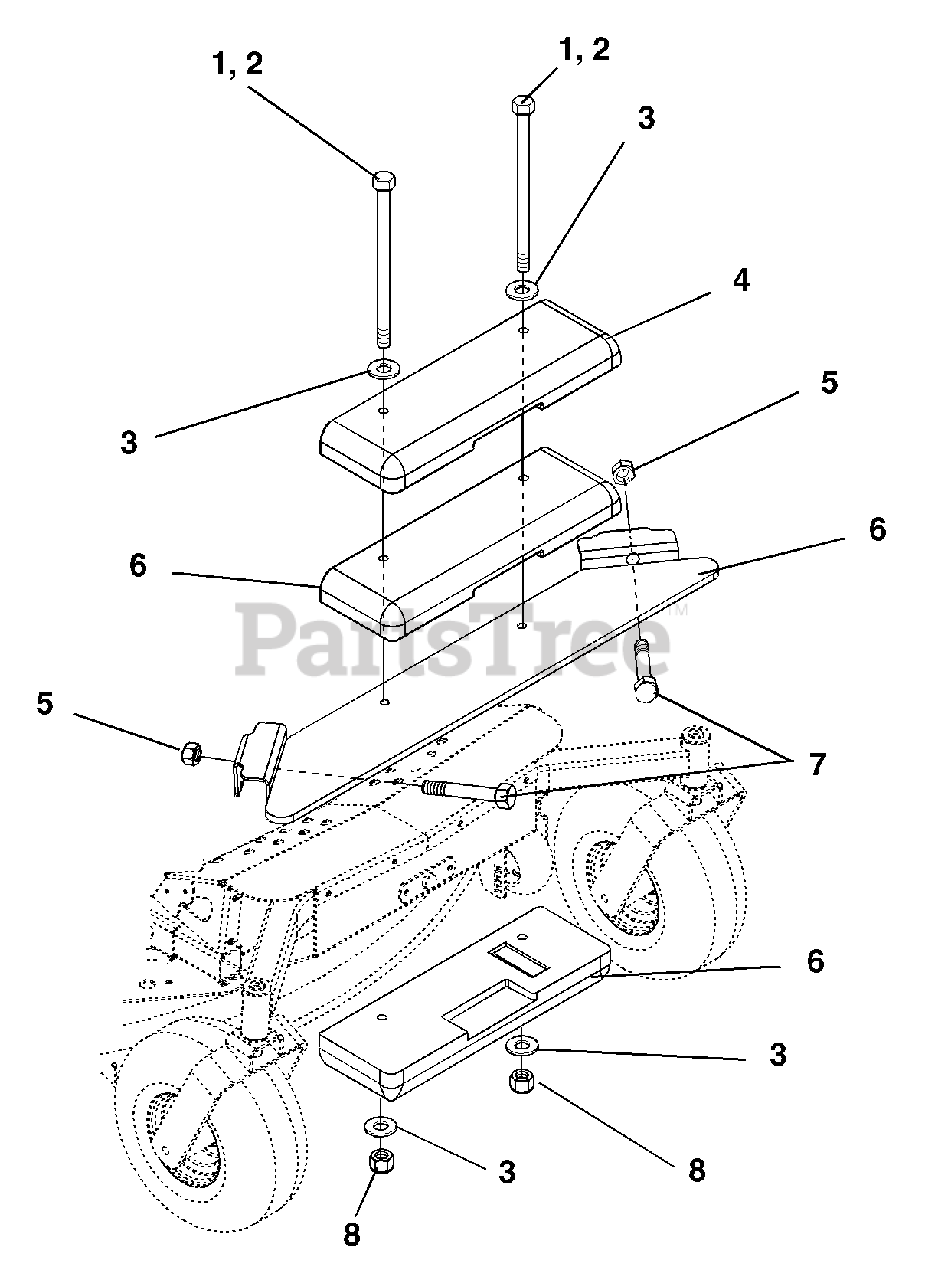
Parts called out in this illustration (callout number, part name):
1	Bolt-Hex .50-13 x 7.50 Grade 5
2	Bolt-Hex .50-13 x 5.50 Grade 5
3	Washer-Flat-Steel .51 x 1.00 x .062
4	Counterweight
5	Nut-Locking .38-16
6	Weldment, Weight Plate
7	Bolt-Hex .38-16 x 3.00 Grade 5
8	Nut-Locking-Center .50-13
